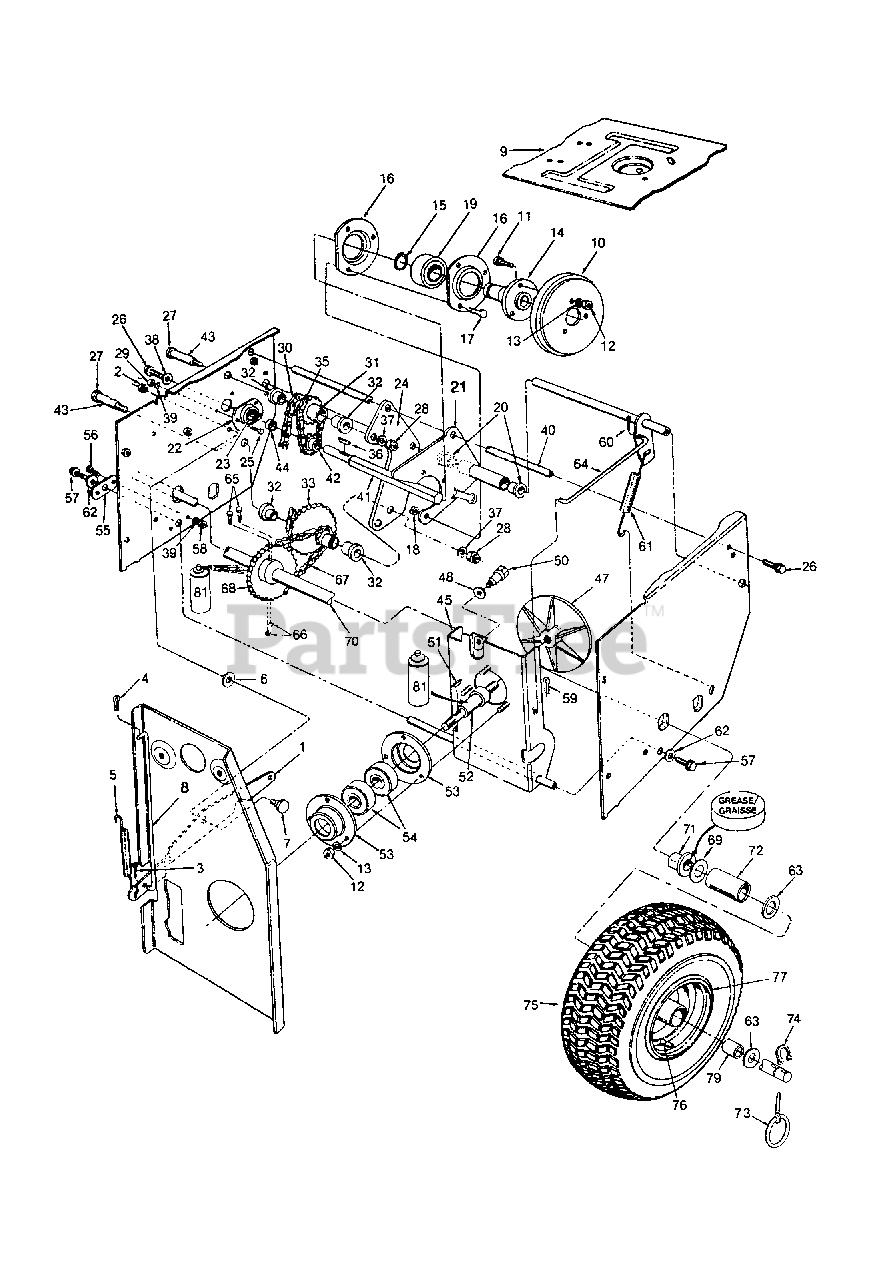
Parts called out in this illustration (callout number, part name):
1	Auger Clutch Bracket
2	Hex Cent. L-Nut 3/8-16
3	Int. Cotter Pin 5/16 Dia.
4	Cotter Pin 3/32 x .75
5	Brake Return Ext. Spring 3.18" Lg.
6	Bell-Wash. .406 I.D. x 1.130 O.D.
7	Shoulder Scr. .625 Dia. x .170
8	Auger Clutch Rod
11	Hex Sems Scr. 5/16-18 x .75
12	Hex Nut 5/16-18
13	L-Wash. 5/16 I.D.
14	Friction Wheel Adapter Plate
15	Snap Ring for 1.0" Shaft
16	Bearing Housing-52 MM
17	Hex Scr. 1/4-28 x .625" Lg.
18	Hex Ins. Jam L-Nut 1/4-28
19	Bearing-25 MM
20	Flange Bearing .63 I.D.
21	Sliding Linkage Bracket Ass'y.
22	Bearing Housing
23	Ball Bearing .5 I.D. x 1.99 O.D. x .44
26	Hex L-Bolt 5/16-18 x .62
27	Hex Screw 3/8-24 x 2.75
28	Hex Nut 3/8-24
29	Hex Nut 1/4-20
30	#420 Chain 1/2 Pitch x 44 Links
31	Sprocket Hub Ass'y. 9 & 14 Teeth
32	Flange Bearing .63 I.D.
33	Sprocket Hub Ass'y.-9 & 32 Teeth
35	#41 Chain .50 Pitch x 20 Links-Endless
36	#4 Hi-Pro Key 3/32 x 5/8
37	Lock Washer Heavy 3/8" I.D.
38	Bell-Washer .345 I.D. x .88 O.D. x .08
39	L-Wash. 1/4 I.D.
40	Sliding Support Axle
41	Hex Shaft
42	Center Sprocket-8 Teeth
43	Sprocket Hub Tubing 3/8 I.D. x 5/8 O.D. x 1.
44	Spacer .51 I.D. x .69 O.D. x .44
48	Bell-Washer .400 I.D. x .88 O.D. x .06
50	Shoulder Screw .498 Dia. x 1.64 Lg.
51	No. 61 Hi-Pro Key 3/16 x 5/8
52	Drive Plate Spindle
53	Brg. Housing 1.65" I.D.
54	Ball Bearing .787 I.D. x 1.85 O.D. x .56
55	Pivot Axle Bracket
56	Hex Screw 1/4-20 x .62
57	Hex L-Bolt 5/16-18 x .62
59	Int. Cotter Pin 5/16 Dia.
60	Cotter Pin 3/32 x .75
61	Idler Extension Spring
62	Fl-Washer .344 I.D. x .875 O.D.
63	Fl-Washer 1.03 I.D. x 1.62 O.D. x .03
64	Drive Clutch Rod .31 Dia. x 7.38
65	Hex Screw 5/16-18 x 1.75
66	Hex Ins. L-Nut 5/16-18
67	Chain #420 .50 Pitch x 38 Links
68	Sprocket Hub Ass'y.-28 Teeth
69	Fl-Washer 1.03 I.D. x 1.62 O.D. x .03
70	Free Wheel Axle 1.0 x 28.03 Lg. (28")
71	Flange Bearing W/Flats
72	Axle Sleeve
73	Klick Pin
74	Snap Ring for 1.0" Shaft
75	Wheel Ass'y. Comp.
76	Air Valve
77	Rim Only
79	Bearing 1.0 I.D. x 1.127 O.D. x 1.00
81	Chain Lube-Belray 6 in 1 or Equivalent
